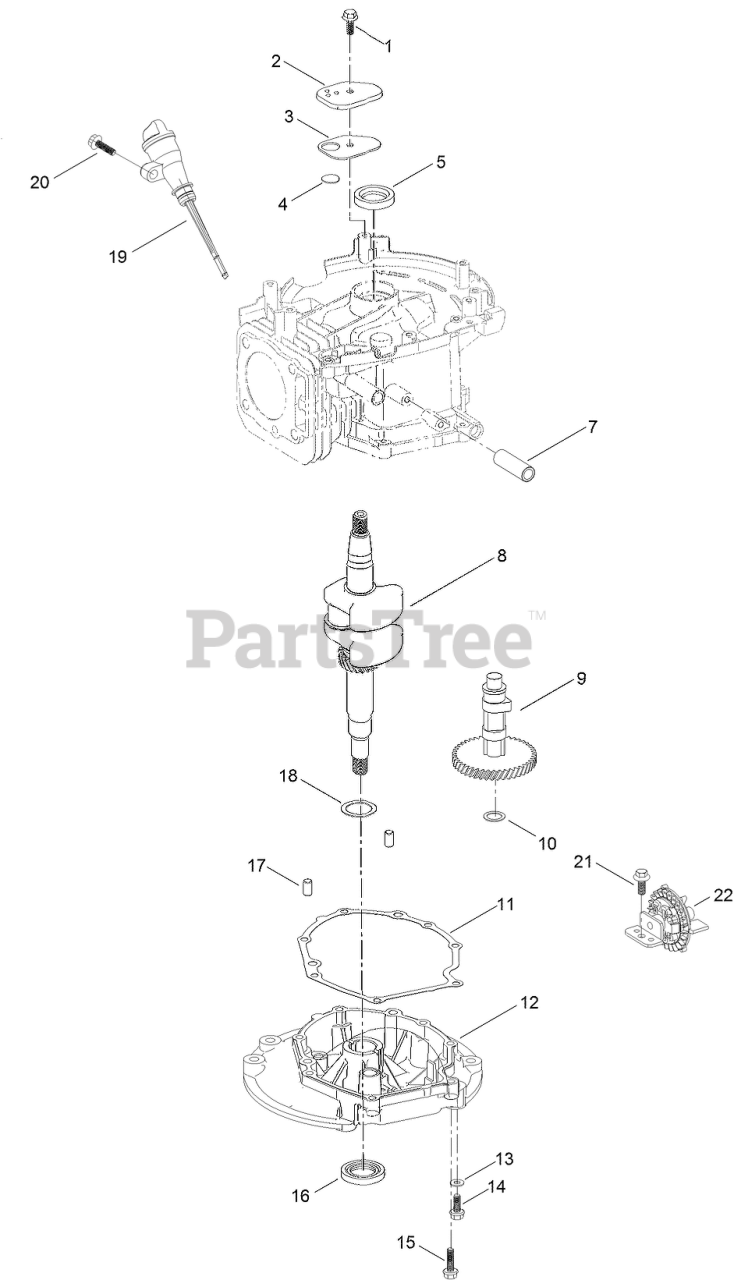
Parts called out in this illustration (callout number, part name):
1	SCREW-HHF
2	COVER-BREATHER
3	GASKET-COVER, BREATHER
4	VALVE-BREATHER
5	SEAL-OIL
7	TUBE-BREATHER
8	CRANKSHAFT ASM
9	CAMSHAFT ASM
10	WASHER-FLAT
11	GASKET-COVER, CASE
12	COVER-CRANKCASE
13	WASHER-PLAIN
14	SCREW-HHF
15	SCREW-HHF
16	SEAL-OIL
17	PIN-DOWEL
18	WASHER-FLAT
19	DIPSTICK AND FILL TUBE KIT
20	BOLT-FLANGE
21	SCREW-HWH, THD FORM
22	GOVERNOR GEAR ASM
